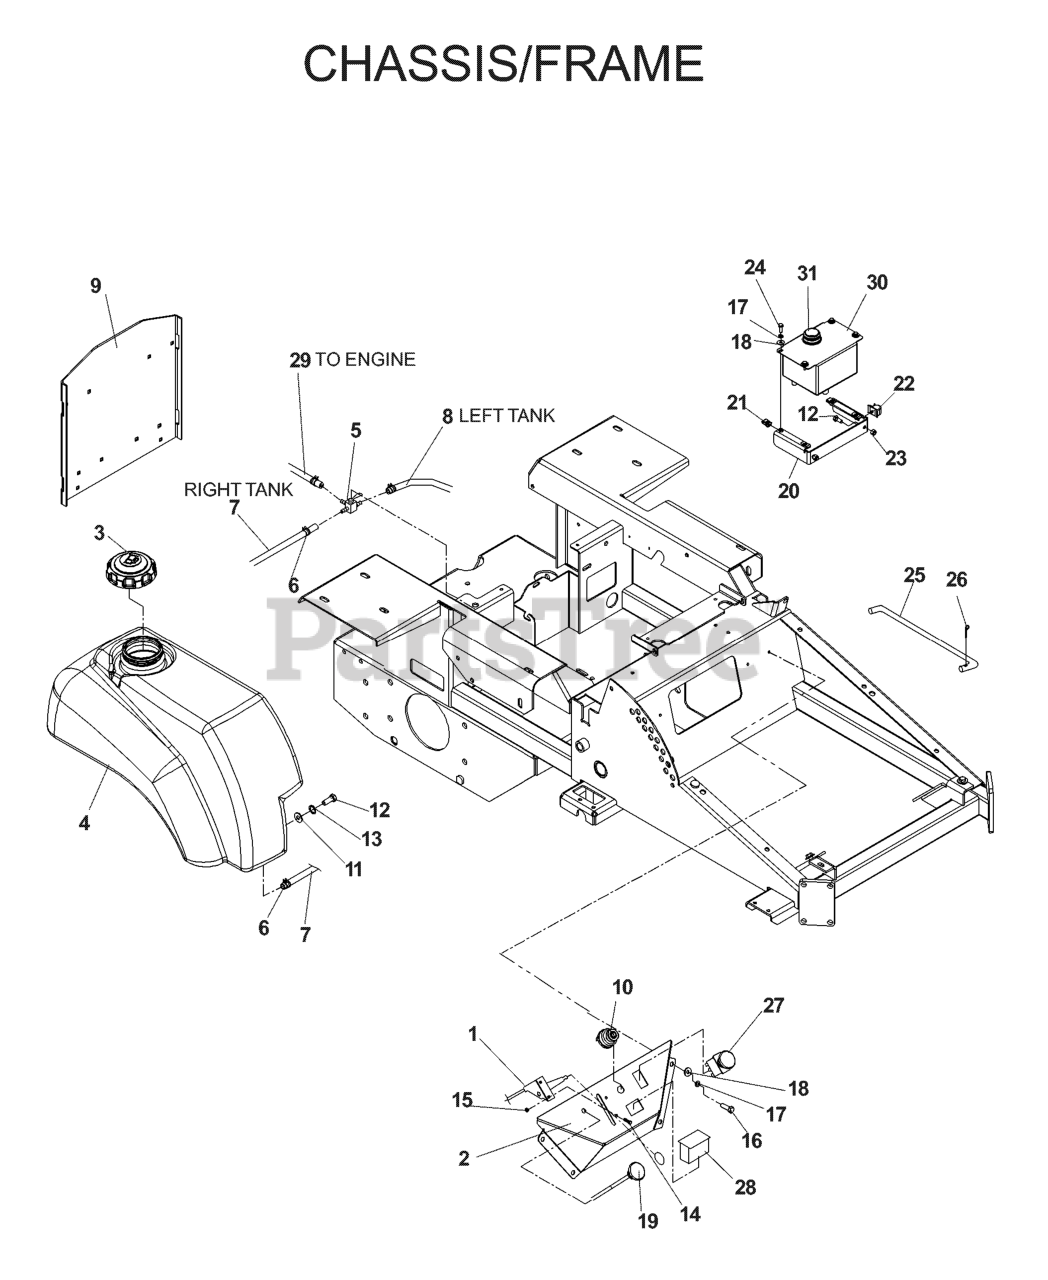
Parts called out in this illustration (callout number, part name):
1	THROTTLE CABLE
2	CONSOLE W/DECALS
3	FUEL CAP ANTI-SPLASH
4	FUEL TANK RT
5	FUEL VALVE
6	HOSE CLAMP
7	FUEL LINE 24"
8	FUEL LINE 34"
9	ENGINE GUARD
10	RP IGNITION SWITCH
11	WASHER 5/16 FLAT
12	HCS 5/16C X 3/4
13	WASHER.LOCK.HVY.HLCL.SPR.5/16
14	HCS #10-24 X 1/2
15	NUT 10-24 NYLOC
16	SCREW 1/4 X 5/8
17	LOCKWASHER 1/4"
18	WASHER 1/4 FLAT
19	CABLE, CHOKE
20	TANK MOUNT
21	1/4C - U TYPE RETAINER
22	PUSH-MOUNT WIRE CLIP
23	NUT 5/16 NYLOC
24	HCS 1/4C X 3/4 HCS
26	RP_COTTER PIN 1/8 X 3/4
27	RP.SWITCH, BLADE
28	HOUR METER
29	FUEL LINE 29.5"
31	HYDRAULIC CAP
